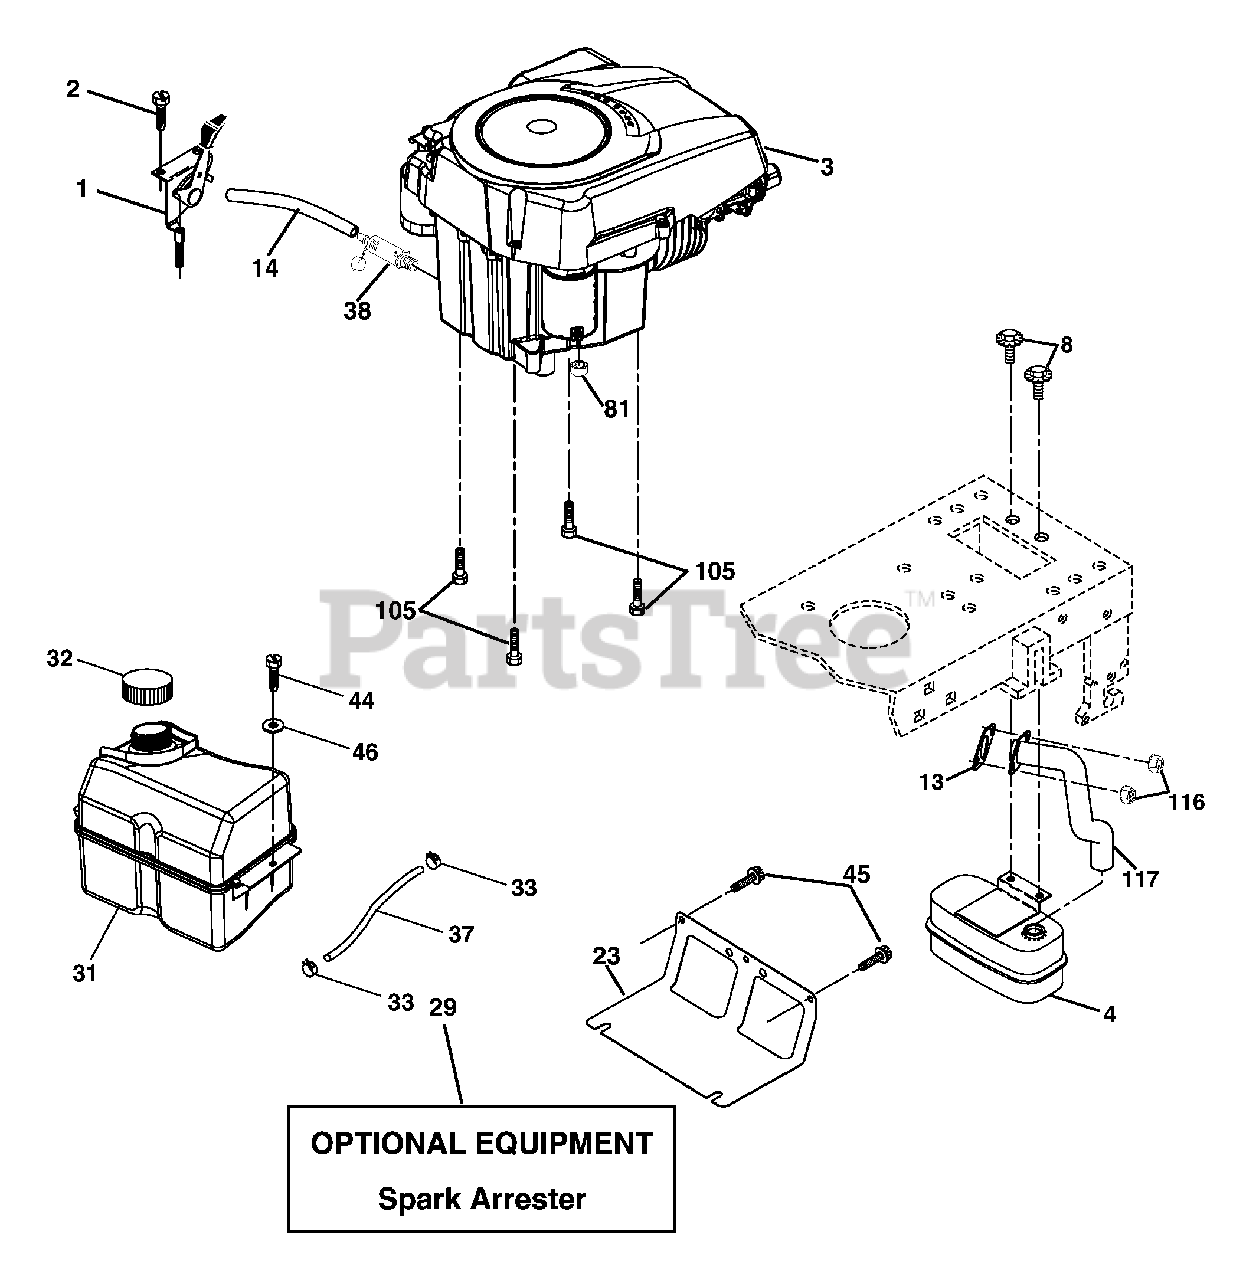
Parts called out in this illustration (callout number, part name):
1	Control, Throttle
2	Screw 10 x 3/4 Single Lead Hex
4	Muffler
8	Bolt 5/16-18 unc x 3/4
13	Muffler Gasket
14	Tube Oil Drain
23	Shield, Browning/Debris Guard
29	Arrester, Spark
31	Tank, Fuel
32	Cap, Fuel
33	Clamp, Hose Blk
37	Line, Fuel
38	Plug Drain Oil Easy
44	Screw Hex Wsh THDROL 1/4-20 x 3/4
45	Screw Hex Wsh Thdrol 3/8-16 x 3/4
46	Washer 9/32 x 7/8 x 16 Ga.
81	Nut Keps Hex 1/4-20 unc
105	Screw 3/8-16 x 1
116	Nut Hex Flange Toplock M8-1.25
117	Tube Exhaust
